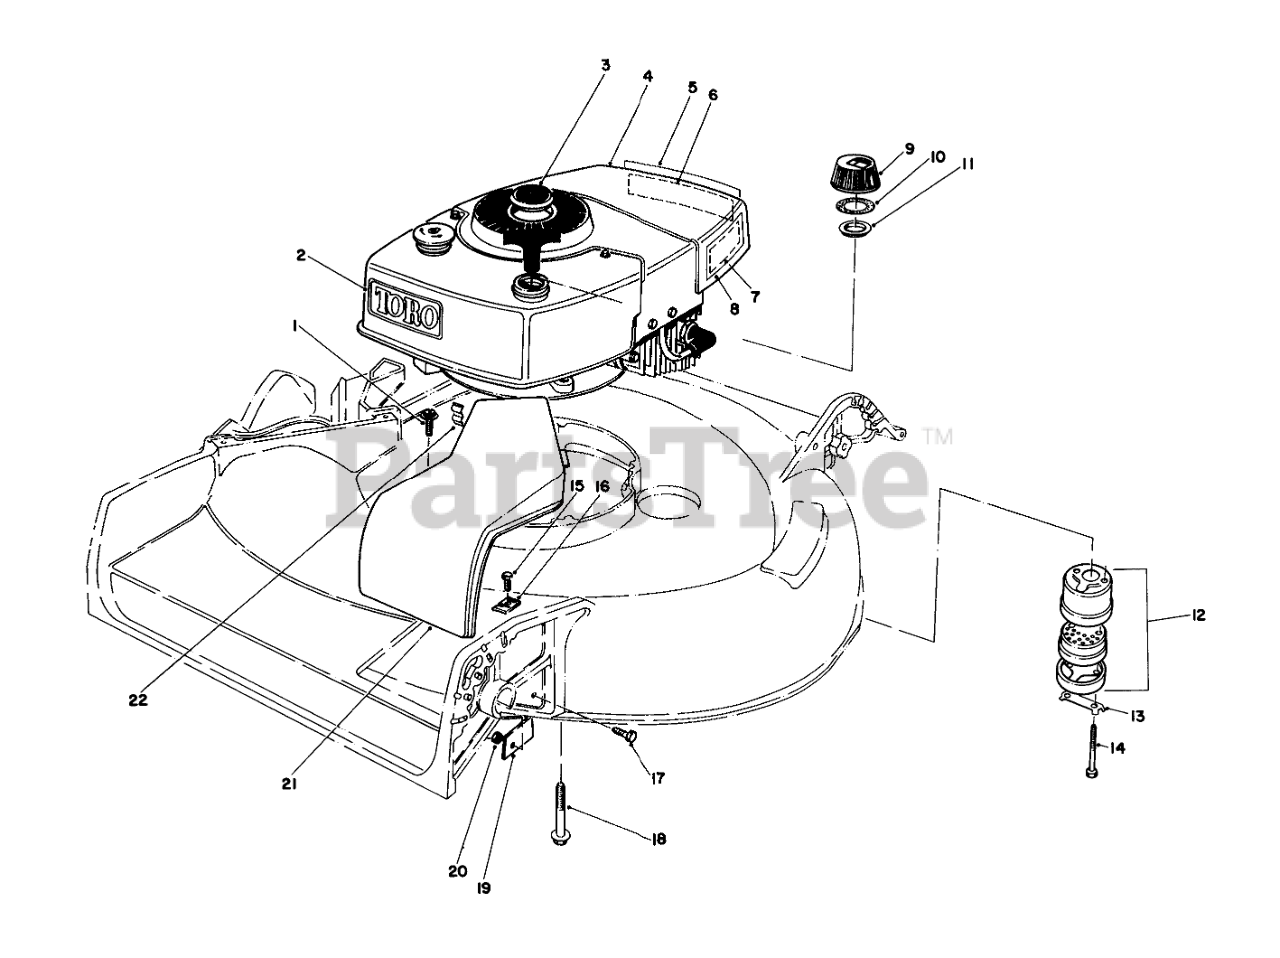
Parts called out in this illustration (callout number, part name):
1	SCREW
2	Decal Tow
3	Plug Button
4	Engine
5	Decal-Danger
6	Decal Maintenance
7	Decal-Maintenance
8	Decal-Maintenance
9	Gas Cap Assembly (Incl. Ref. #10 & 11)
10	GASKET
11	GAS CAP BAFFLE
12	Muffler (Incl. Ref. #13 & 14)
13	CLIP - LOCKING
14	SCREW-HH
15	SCREW-HWHTF
16	Cable Clamp
17	SCREW-HH
18	3/8-16 X 2-3/4 CAPSCR
19	Shield Front
21	Cover-Belt Drive
22	Clip Conduit
